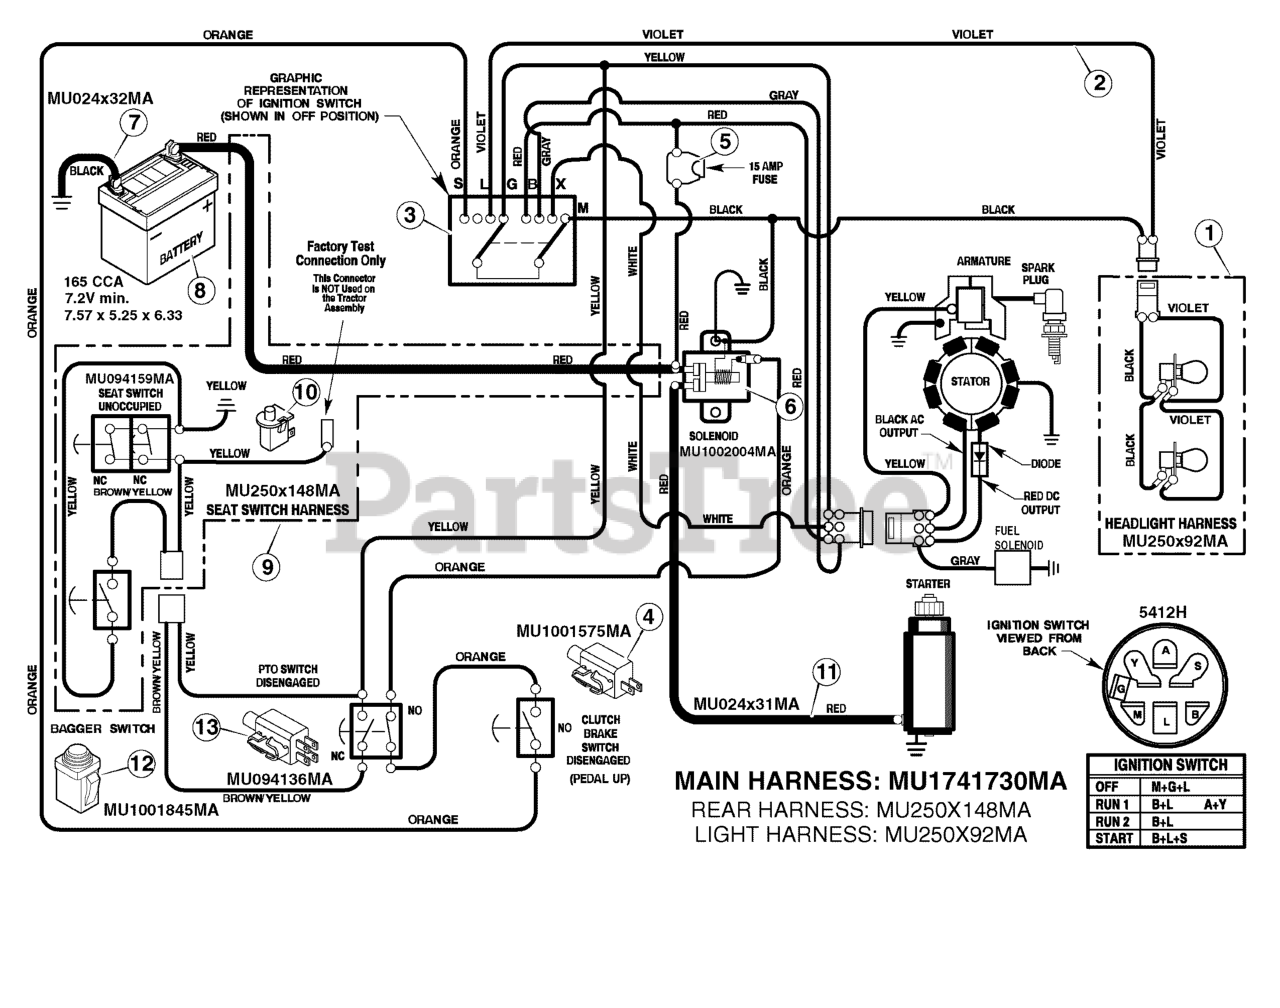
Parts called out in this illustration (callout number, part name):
1	HARNESS, Light Wire
2	HARNESS, Chassis Wire
3	SWITCH, Ignition
4	SWITCH, Limit
7	CABLE, Battery Ground
8	BATTERY
9	HARNESS, Seat Switch Wire
10	SWITCH, Seat Sensor
12	SWITCH, Bag Sensor
13	SWITCH, Limit
